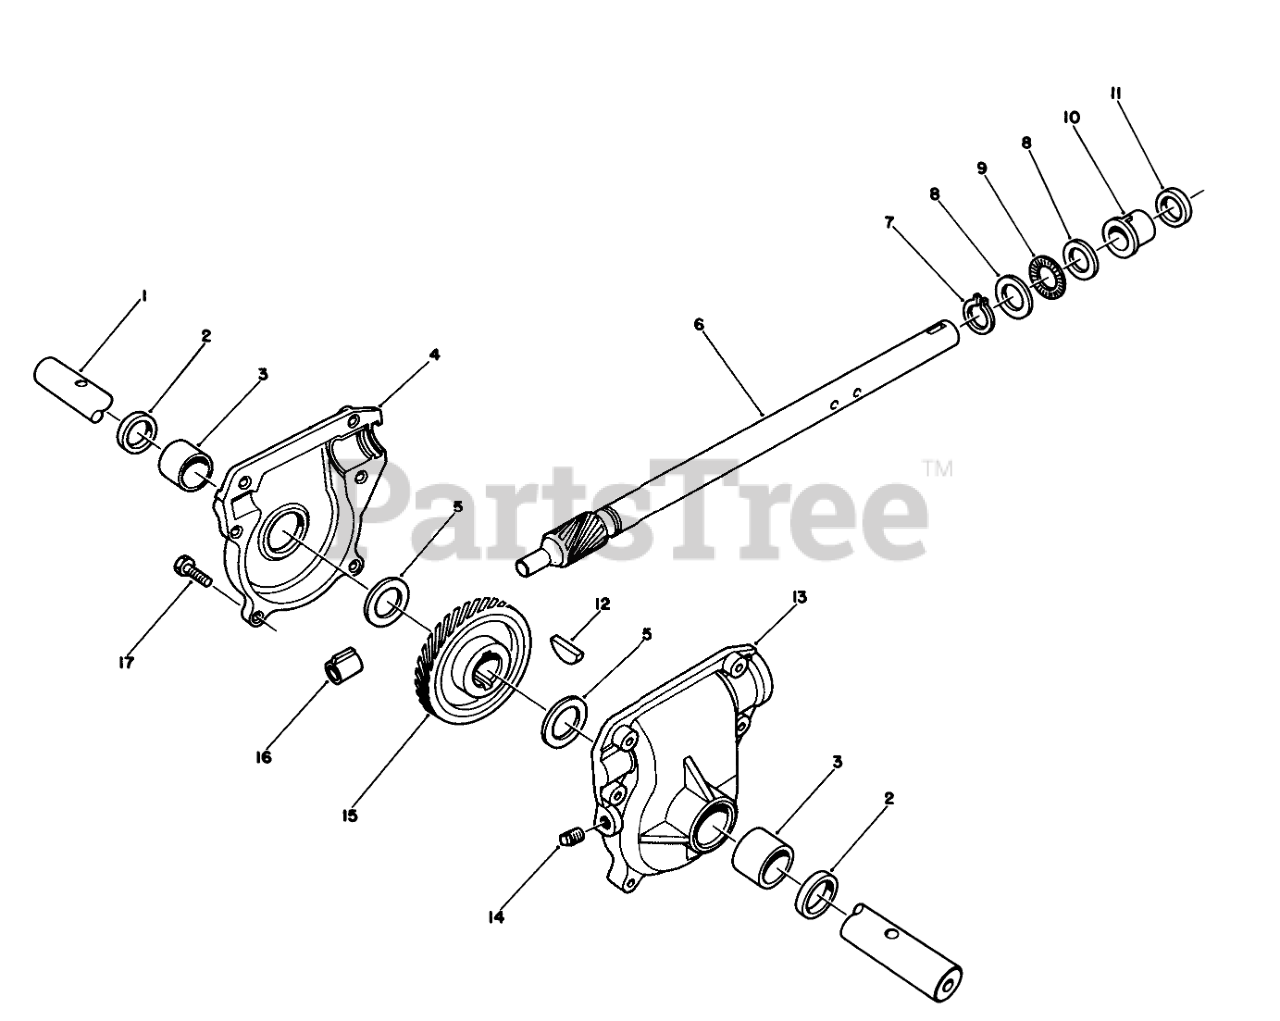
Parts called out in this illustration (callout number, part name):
1	SHAFT-AUGER
2	SEAL-OIL
3	BUSHING
4	Gearcase Assembly-R.H. (Incl. Ref. #2-3)
5	WASHER-THRUST
6	Shaft-Impeller
7	RING-RETAINING, Ext
8	WASHER-THRUST
9	BEARING-THRUST
10	BUSHING-INPUT
11	SEAL-OIL
12	KEY-WOODRUFF
13	Gearcase Assembly-L.H. (Incl. Ref. #2-3)
14	PLUG-PIPE, SQH
15	GEAR-HELICAL
16	BUSHING-WORM
17	SCREW-HWHTF
